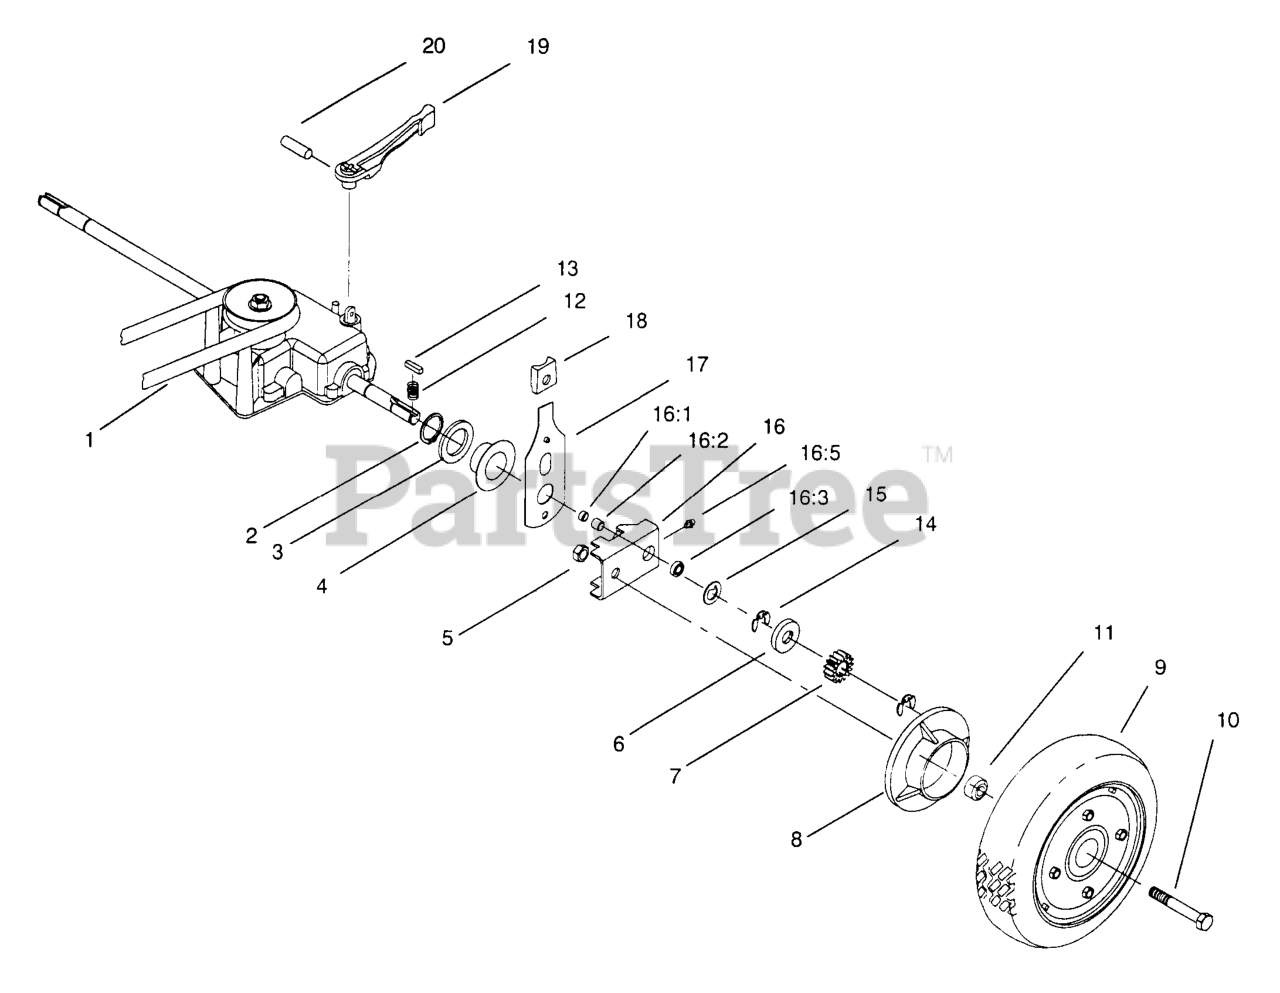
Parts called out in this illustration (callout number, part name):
1	V-BELT
2	RING-RETAINING
4	CAP-END
5	NUT-LOCK, CONE
6	WASHER-THRUST, OUTER
7	GEAR-PINION
8	COVER-WHEEL
10	SCREW-HH
11	SPACER-COVER, WHEEL
12	SPRING-COMPRESSION
14	RING-RETAINING
15	WASHER-THRUST, OUTER
16	PIVOT ARM ASM
16:1	SEAL-OIL
16:3	BEARING-WHEEL
17	REAR SPRING ARM ASM
18	KNOB-ARM
19	LEVER-SHIFT
20	PIN-SPRING
